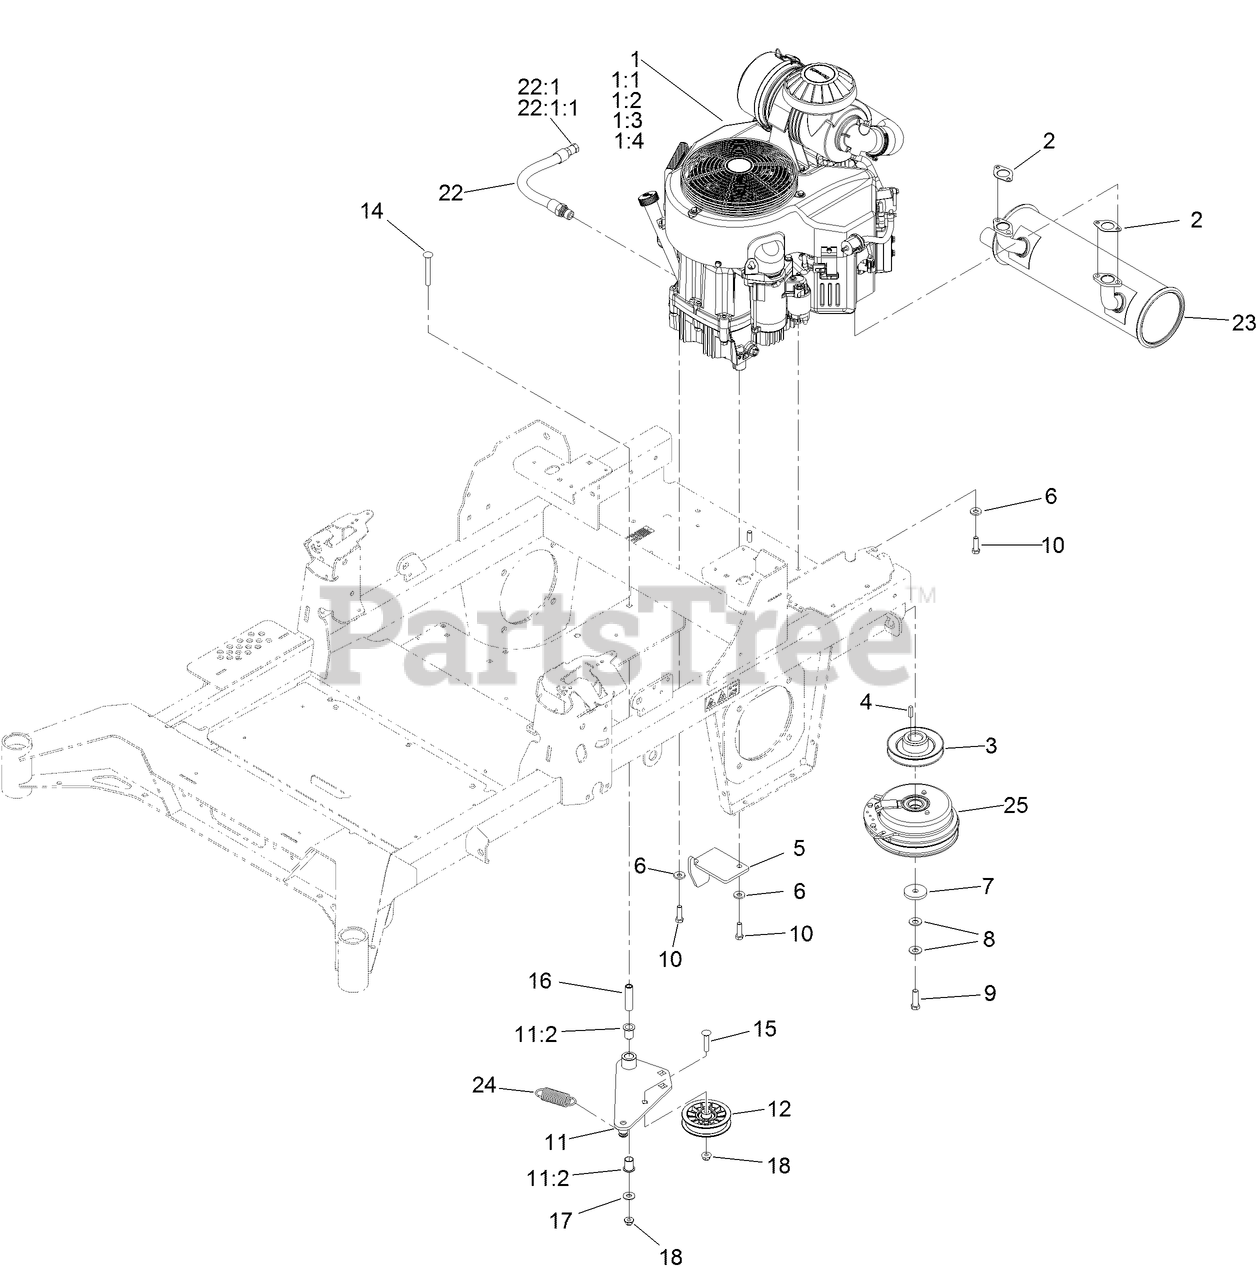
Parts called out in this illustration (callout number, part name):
1	ENGINE-KAWASAKI, FX751V-S07-R
1:1	KAWASAKI 49065-2078 ENGINE OIL FILTER
1:2	KAWASAKI 49019-0031 FUEL FILTER
1:3	KAWASAKI 11013-7039 SAFETY FILTER
1:4	KAWASAKI 11013-7038 AIR FILTER
2	GASKET-EXHAUST
3	SHEAVE, W/HUB
5	ANCHOR-CLUTCH
6	WASHER-BELLEVILLE
7	WASHER-CLUTCH
8	WASHER-SPRING
9	SCREW-HH, W/LOCTITE
10	SCREW-HH
11	IDLER ARM ASM
11:2	BUSHING-FLANGE
12	PULLEY-FLAT IDLER
14	SCREW-CARR
15	SCREW-CARR
16	BUSHING, IDLER PIVOT
17	WASHER-FLAT
18	NUT-HF, NI
22	ENGINE OIL DRAIN HOSE ASM
22:1	PLUG-HH
22:1:1	O-RING
23	MUFFLER
24	SPRING-IDLER
25	CLUTCH
